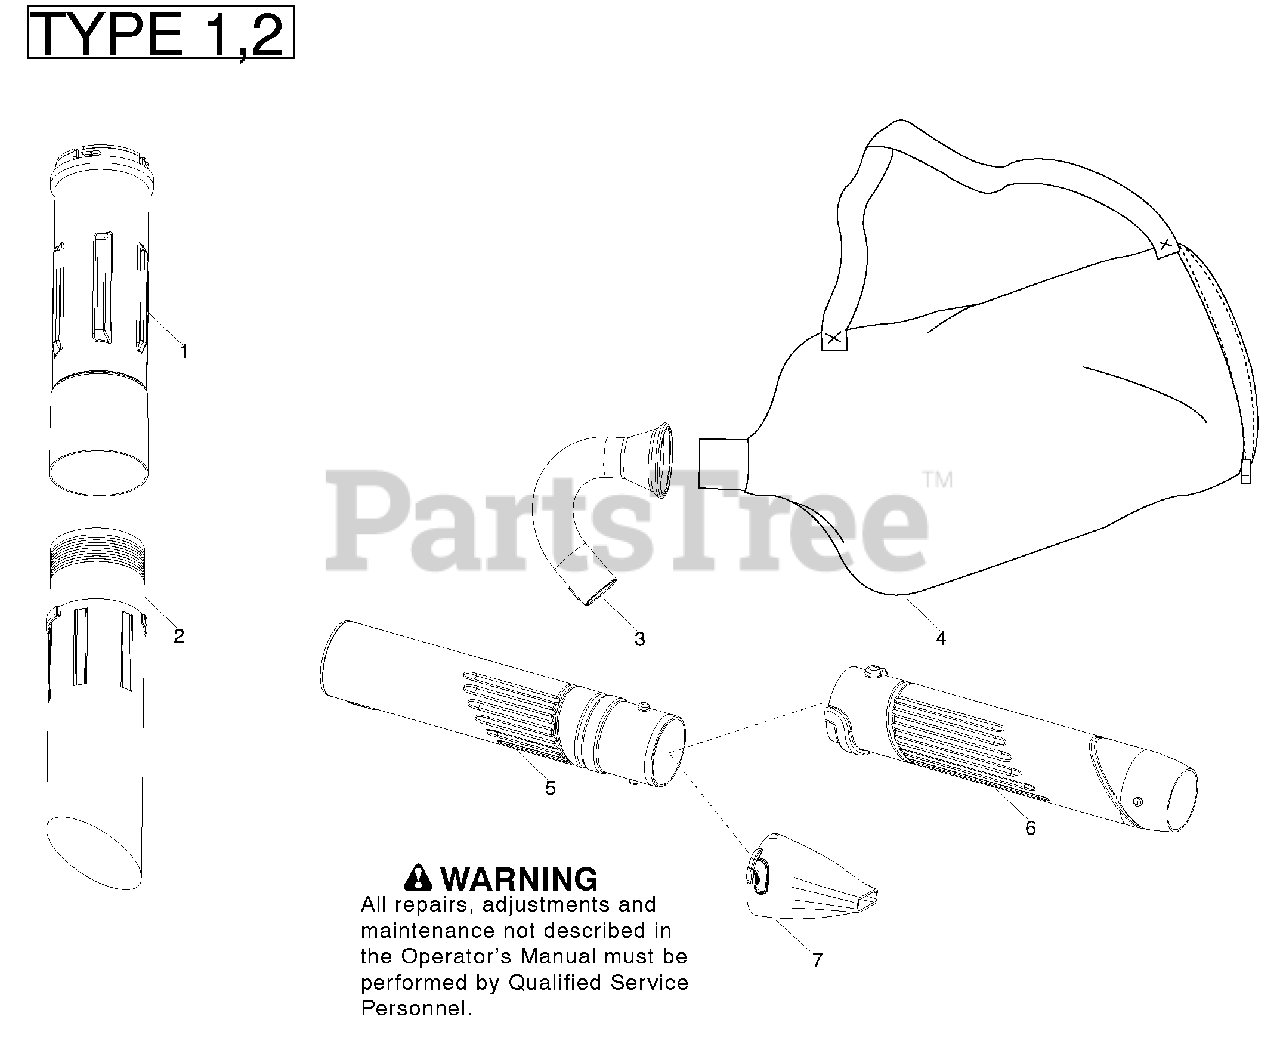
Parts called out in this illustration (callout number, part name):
1	Tube - Upper Vac
2	Tube - Lower Vac
3	Tube - J
4	Assy - Vac Bag
5	Tube - Upper Blower
6	Tube - Lower Blower
7	Nozzle - High Speed
